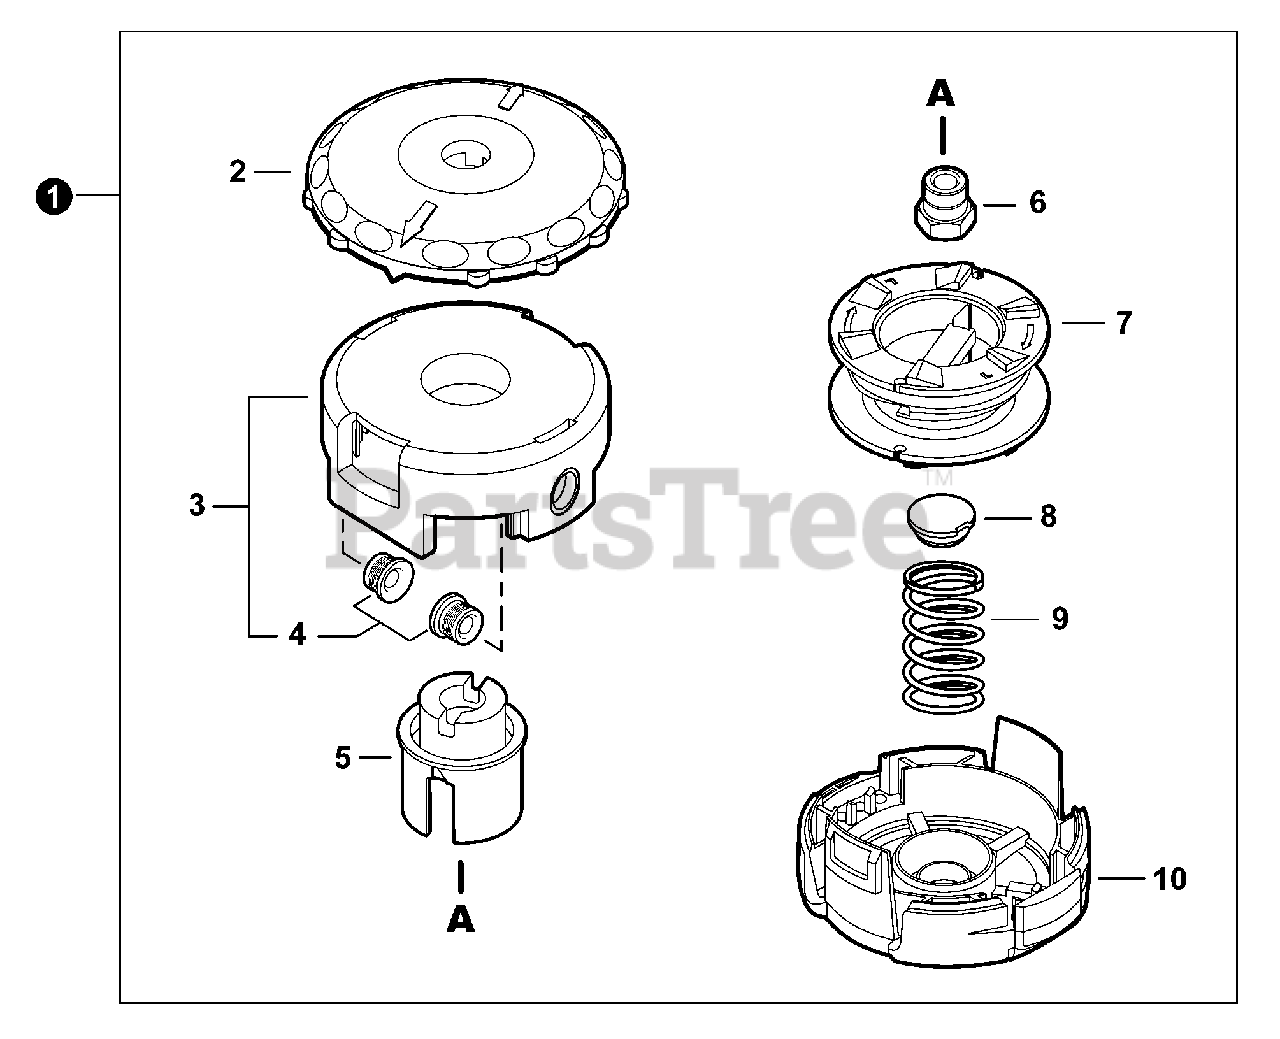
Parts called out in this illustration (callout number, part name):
1	TRIMMER HEAD, SPEED-FEED 400
3	HOUSING ASSY, SPOOL
5	HUB (RH) WHITE
6	BUSHING 3/8-24 RH BLACK
8	CAP, SPRING
9	SPRING, GOLD
10	COVER, SPOOL
